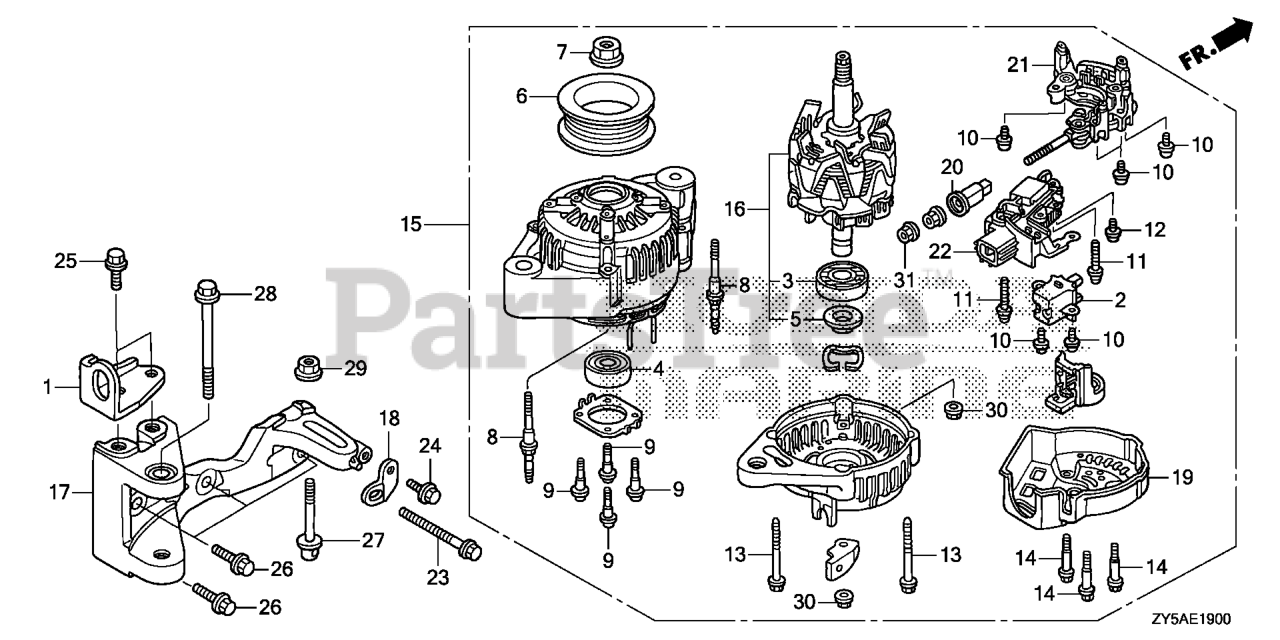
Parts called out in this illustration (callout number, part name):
1	HANGER B, ENGINE
2	HOLDER ASSY., BRUSH
3	BEARING, RR.
4	BEARING, FR.
5	COVER, BEARING
7	NUT, PULLEY LOCK
8	BOLT, STUD
10	SCREW-WASHER
11	SCREW-WASHER (4X25)
13	BOLT-WASHER
15	ALTERNATOR ASSY.
16	ROTOR ASSY.
17	BRACKET, ALTERNATOR
18	STAY, ALTERNATOR
19	END COVER, RR.
20	BUSH, INSULATION
21	RECTIFIER ASSY.
22	REGULATOR ASSY.
23	BOLT, SPL ADJ
23	BOLT, SPECIAL ADJUSTER
24	BOLT, FLANGE (6X16)
25	BOLT, FLANGE (8X20)
26	BOLT, FLANGE (8X28)
27	BOLT, TENSIONER
28	BOLT, FLANGE (10X80)
29	NUT, FLANGE (8MM)
30	NUT-WASHER (5MM)
31	NUT, HEX. (6MM)
